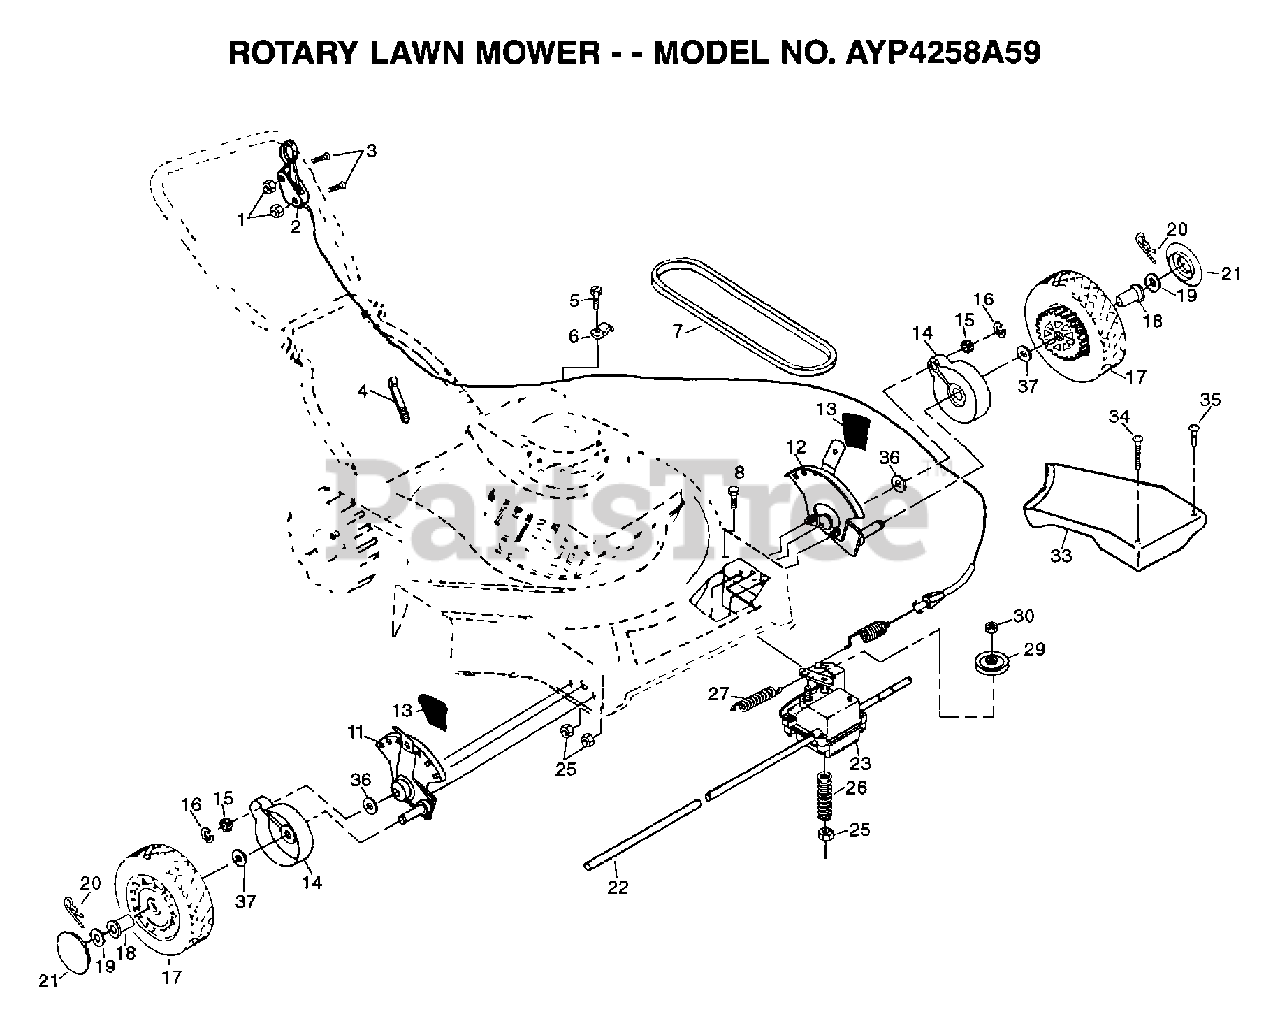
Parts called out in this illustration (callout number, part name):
1	LOCKNUT
2	CONTROL.DRIVE
3	SCREW
5	TAPPING SCREW
6	GUIDE CLIP PM
8	BOLT.1/4-20X2.0
14	DUST SHROUD PM
15	PINION.GEAR
16	E-RING.7/16.RE.
17	WHEEL.8X2.LP.PR
18	BUSHING.HEX
19	WASHER
20	RETAINER CLIP PM
21	HUB CAP
22	DRV SHAFT TUBE PM
26	SPRING.TENSION
27	SPRING
29	PULLEY.DRIVEN
30	LOCKNUT
33	COVER DRIVE BLK
36	WASHER PM
37	WASHER FLUT
